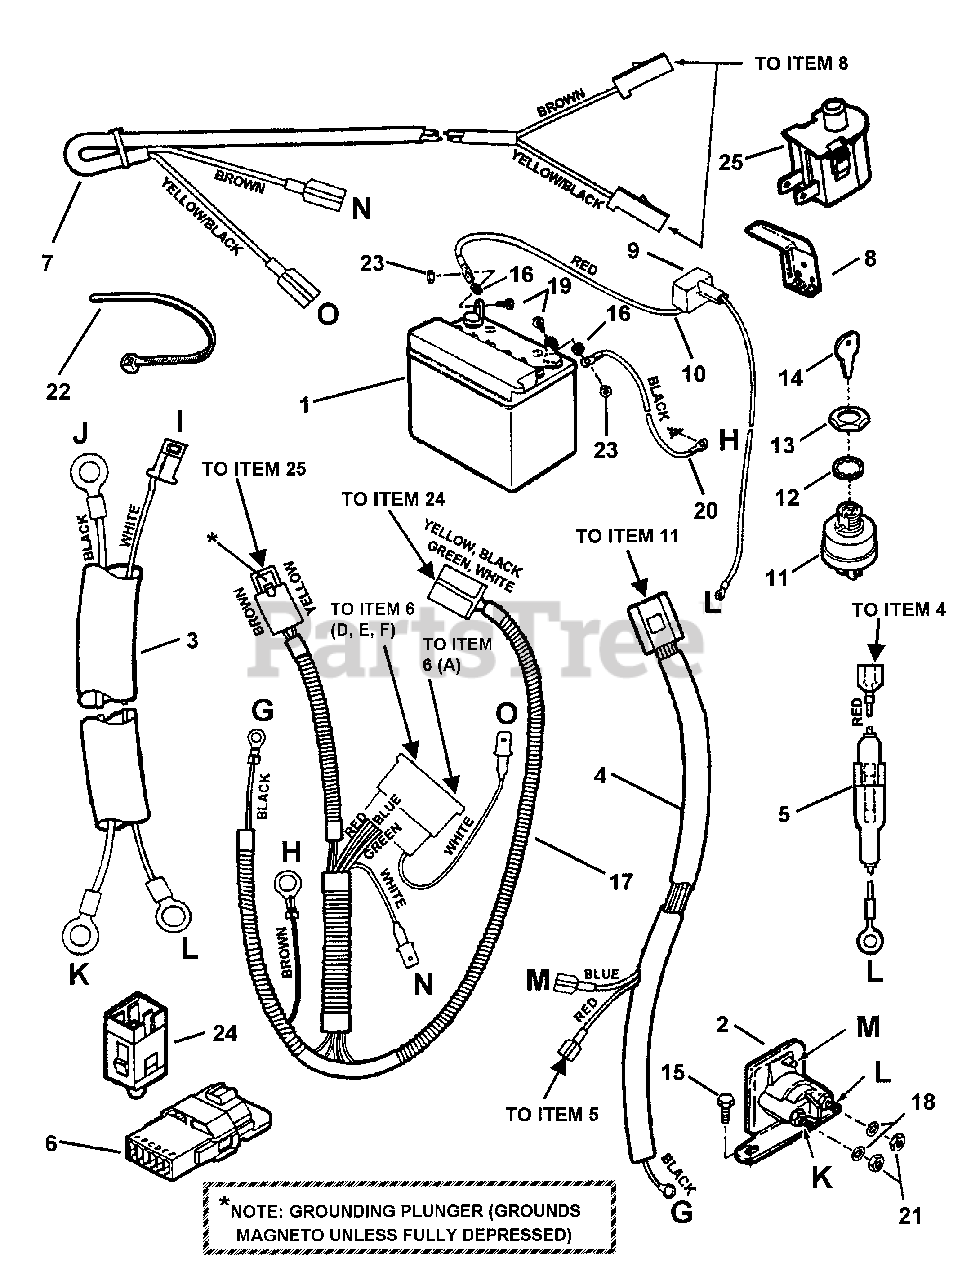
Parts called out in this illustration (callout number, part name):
1	KIT, Battery, 12V, U-1-7RS, 220CCA Dry Charge Snapper No Spill
2	SOLENOID
3	HARNESS, Starter Wiring
4	HARNESS, Ignition Wiring
5	HOLDER, Fuse
6	INTERLOCK Module (Briggs)
7	HARNESS, Deck Interlock Wiring
8	SWITCH, Deck Interlock (NO)
9	COVER, Battery Cable
10	CABLE, Positive (Red) (17" Long)
11	SWITCH, Ignition
12	WASHER, 5/8" Internal Tooth Lock
13	NUT, 5/8-32 Hex
14	KEY, Switch
15	SCREW, 1/4-20 x 1/2" Hex Washer Self-Tap
16	RETAINER, 1/4" Bolt
17	HARNESS WIRE (Operator Presence Control)
18	WASHER, 1/4 Internal Tooth Lock
19	SCREW, 1/4-20 x 5/8" Hex Head Cap, Grade 5
20	CABLE, Negative, Black (15" Long)
21	NUT, 1/4-20 Hex Grade 5 or B
22	TIE, 7" Long Cable
23	NUT, 1/4-20 Hex Center Lock, Grade 5 or B
24	SWITCH, Operator Presence Control (OPC) Traction (NO/NC)
25	SWITCH, Seat (NC)
